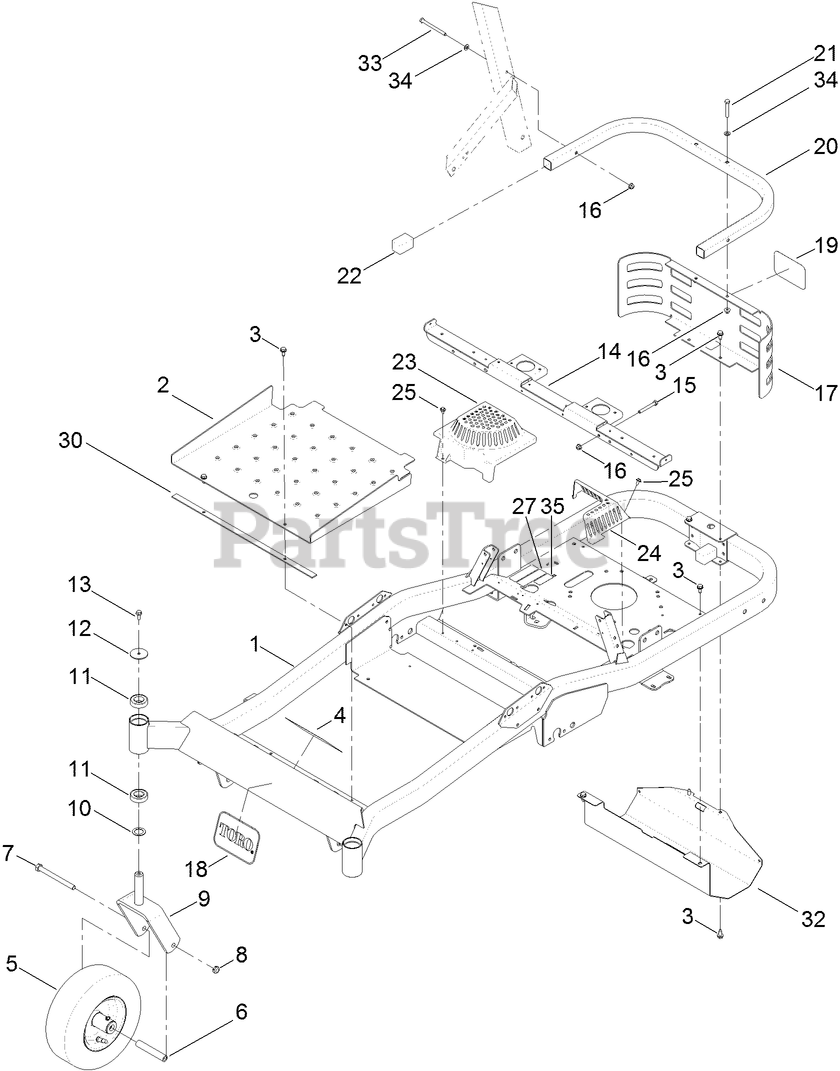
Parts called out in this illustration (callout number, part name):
2	PAN-FLOOR
3	SCREW-HWHTF
4	DECAL-SAFETY
5	WHEEL AND TIRE ASM
6	SPACER-SPANNER
7	SCREW-HH
8	NUT-HEX
9	FORK-CASTER
10	WASHER-THRUST
11	BEARING-BALL
12	WASHER
13	SCREW-HHF
14	SUPPORT-SEAT
15	SCREW-HH
16	NUT-HF, NI
17	GUARD-REAR
18	DECAL
20	TUBE-GUARD
21	SCREW-HH
23	COVER-FAN, RH
24	COVER-FAN, LH
25	SCREW-HHFTF
27	DECAL-EMISSIONS, E P A
30	STRIP-VIBRATION, ANTI
33	SCREW-HH
34	WASHER-PLAIN
35	DECAL-LOCATION, SERVICE DEALER
